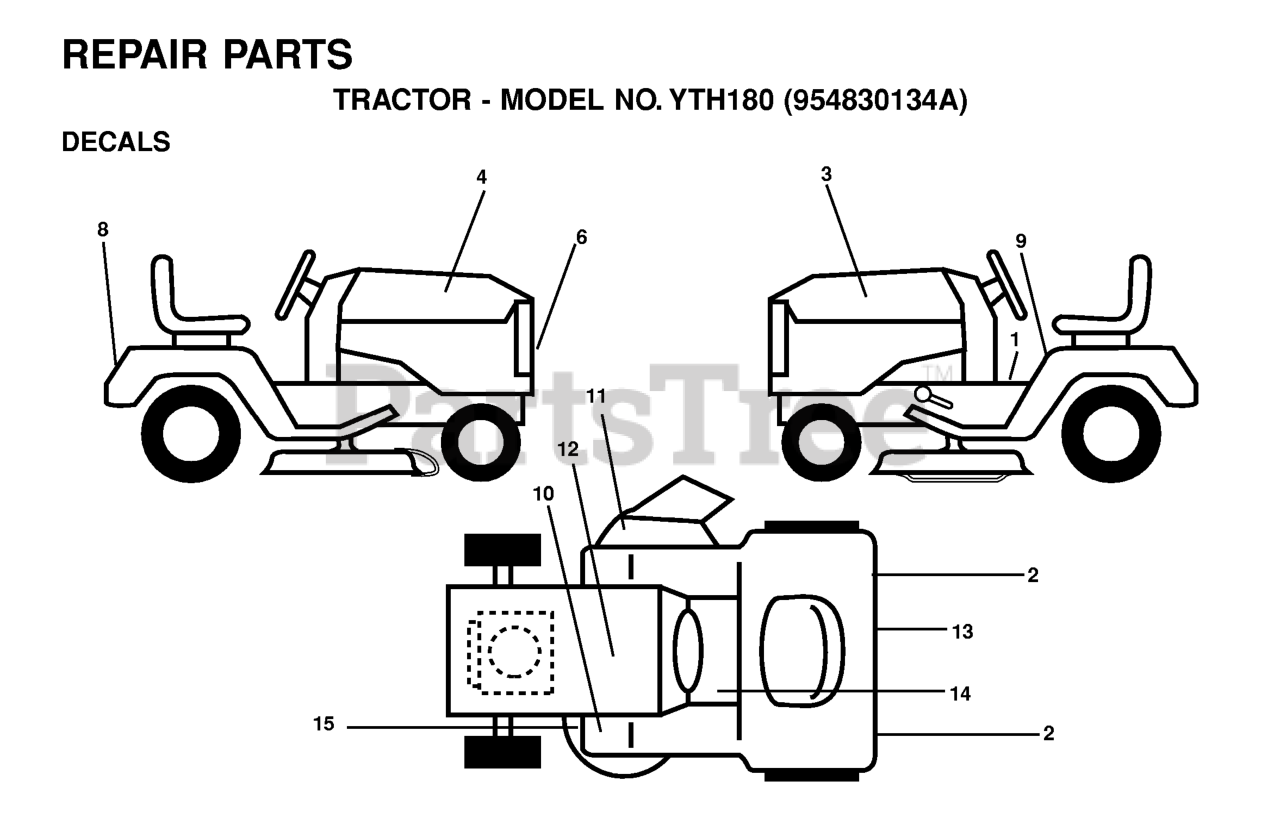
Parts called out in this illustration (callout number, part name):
1	DECAL DASH
2	REFLECTOR-TAIL YT
3	DECAL L.H. YTH180
4	DECAL R.H. YTH180
6	DECAL.GRILLE.HUSQ
8	DECAL FENDER HUSQ
9	DECAL CAUTION
11	DECAL WARNING (ENGLISH/FRENCH)
12	DECAL BTRY SYMBOLS
13	DECAL DRAWBAR CONTROL
